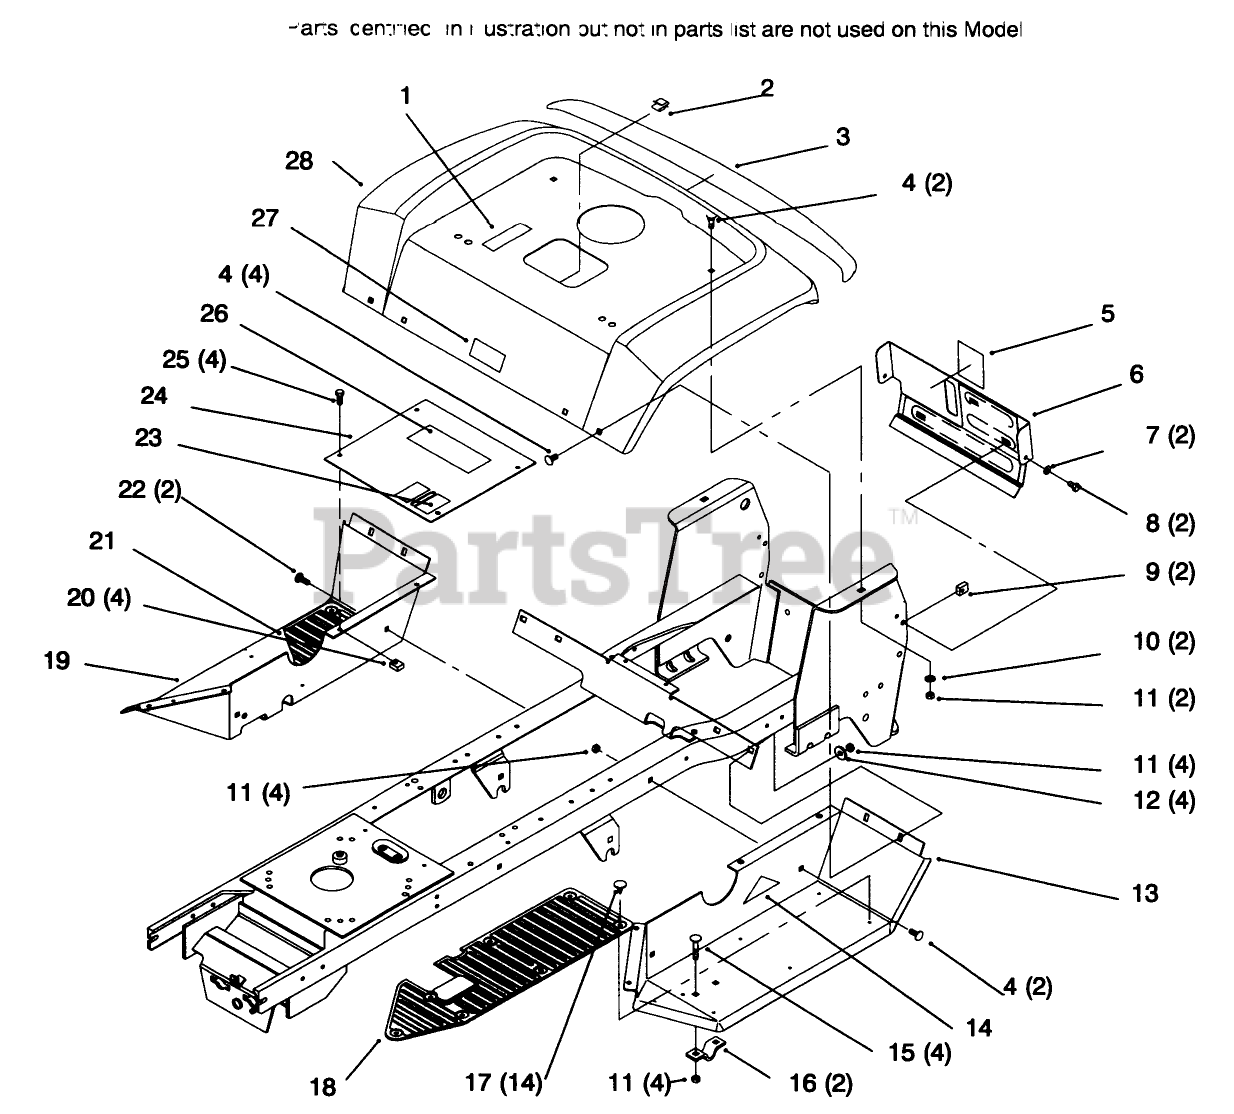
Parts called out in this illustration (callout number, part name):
2	CLIP-RETAINER, WIRE
3	DECAL - REAR FENDER
4	BOLT-CARR
5	DECAL-LEVEL, FUEL
7	WASHER-FLAT
8	SCREW-HH
9	NUT-SPEED
10	WASHER-PLAIN
11	NUT-LOCK, NI
12	WASHER
13	FOOTREST-LH
16	CLAMP
17	FASTENER-PANEL
18	FOOTPAD-LH
19	FOOTREST-RH
21	FOOTPAD-RH
22	SCREW-CARR
23	DECAL - HOC
24	PLATE/DECAL ASM-FOOTREST
25	SCREW-HH
26	DECAL-DANGER
27	DECAL - USA
29	SCREW-CARR
